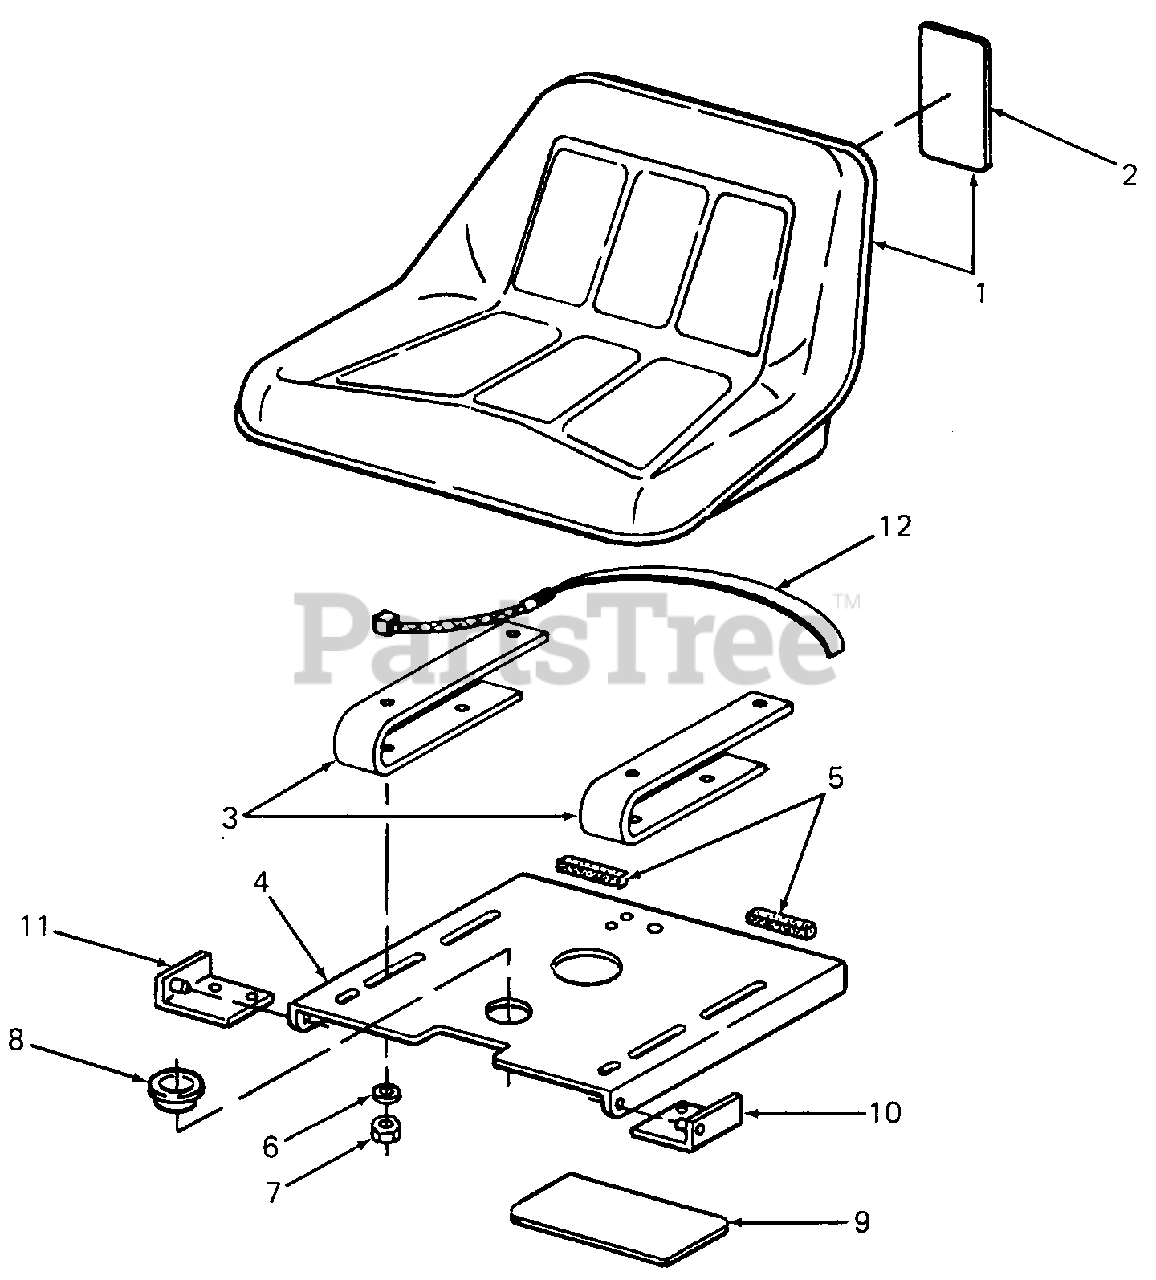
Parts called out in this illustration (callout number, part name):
1	Seat w/Graphic
2	Graphic, Caution
3	Spring, Seat
6	Washer, Bell, .345 X .88 X .06 Thk
7	Nut, Hex, 5/16-18 GR5
8	Bushing, Snap
9	Label, Fuel Warning
12	Switch Assy, Beam
